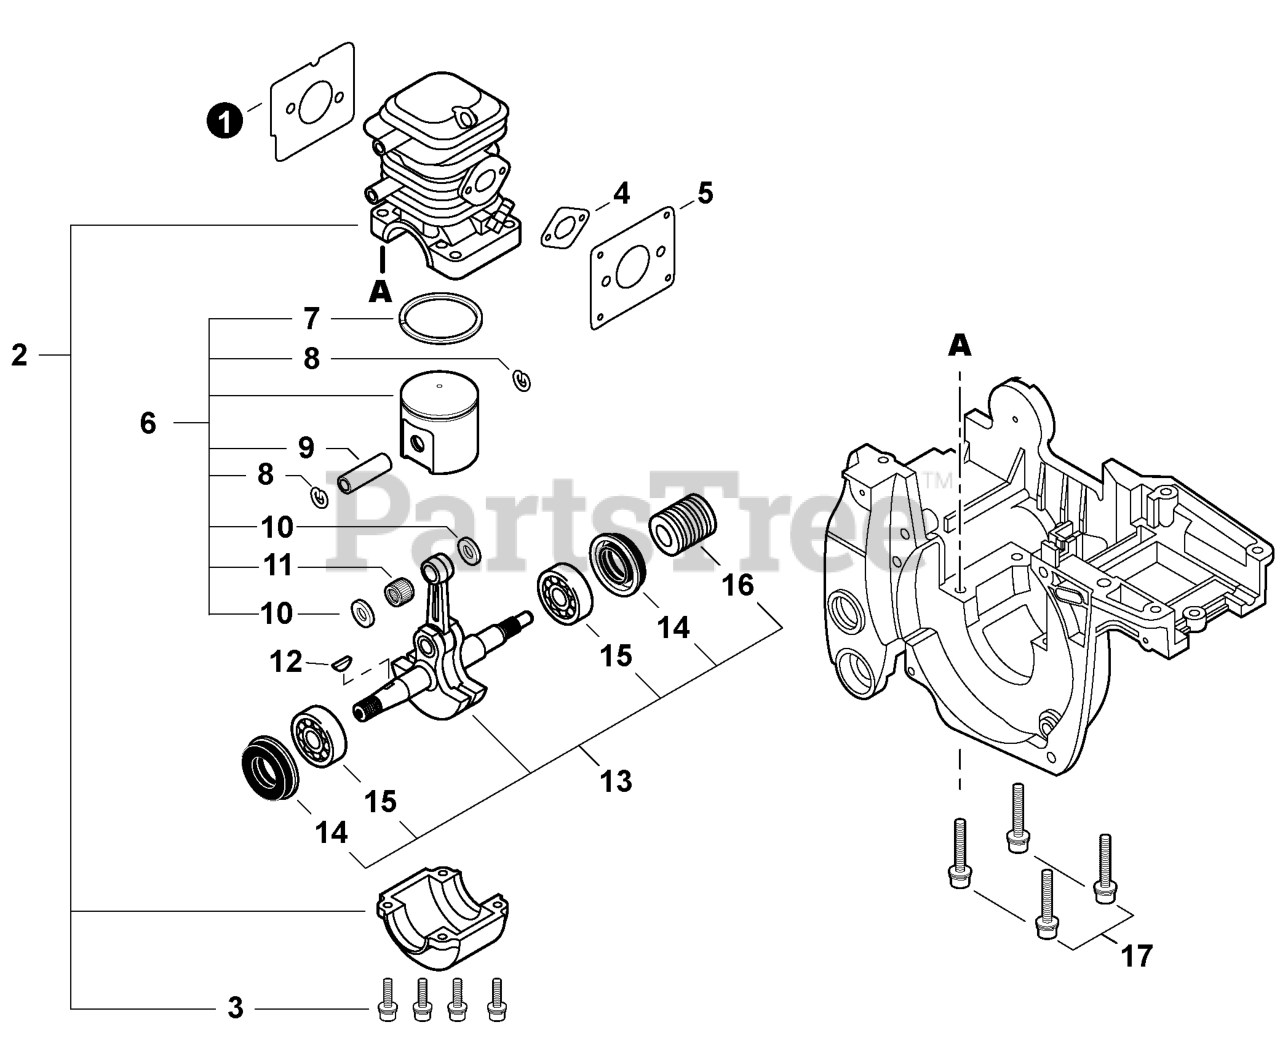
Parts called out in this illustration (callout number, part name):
1	GASKET, EXHAUST
2	CRANKCASE KIT
3	BOLT 5x22
4	GASKET, INTAKE
5	GASKET, INTAKE
6	PISTON KIT
7	RING, PISTON
8	RING, SNAP
9	PIN, PISTON 9
10	WASHER, THRUST
11	BEARING, NEEDLE 9
12	KEY, WOODRUFF
13	CRANKSHAFT ASSY
14	SEAL, OIL 12
15	BEARING, BALL 6201
16	GEAR, WORM
17	BOLT 5x30
